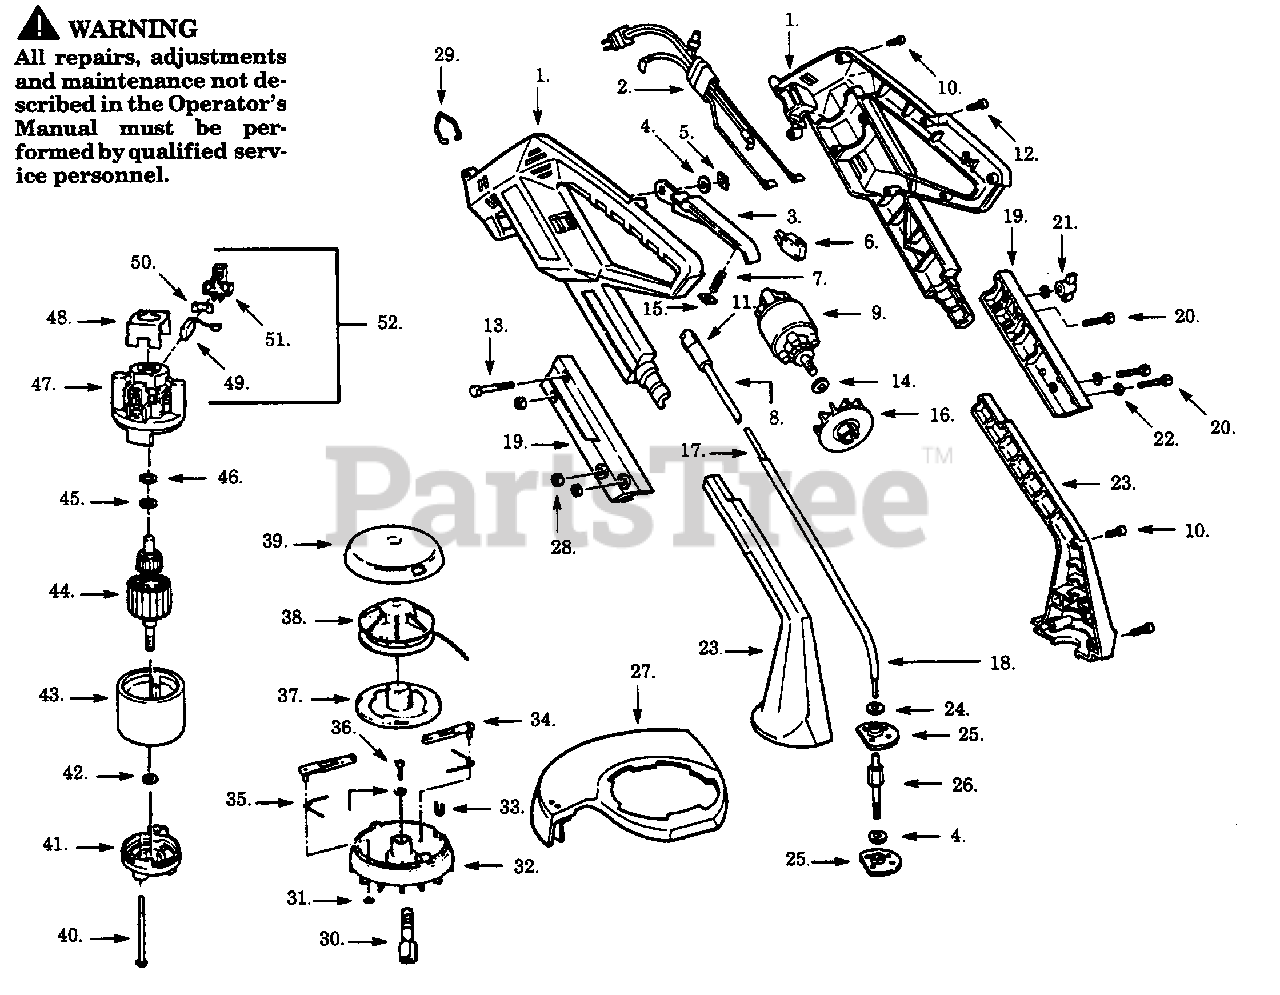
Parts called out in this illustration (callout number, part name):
1	Motor Hsg. Set
2	Harness Ass'y.
4	Washer, (As required)
5	Push Nut
7	Trigger Spring
8	Upper Sleeve
9	Motor Ass'y.
15	Square Nut
17	Flex Shaft Ass'y.
19	Housing Set
23	Spindle Housing Set
24	Felt Washer
25	Bearing Holder
26	Shaft Adapter
27	Guard Ass'y.
30	Shaft Adapter
33	Line Saver
38	Spool w/Line
41	Endbell Ass'y. (Drive)
43	Field Ass'y.
44	Armature Ass'y.
45	Washer (As required)
47	Endbell Ass'y. (Brush)
48	Insulator
50	Brush Spring
51	Brush Holder
52	Brush Kit (Incl. 49,50,51)
